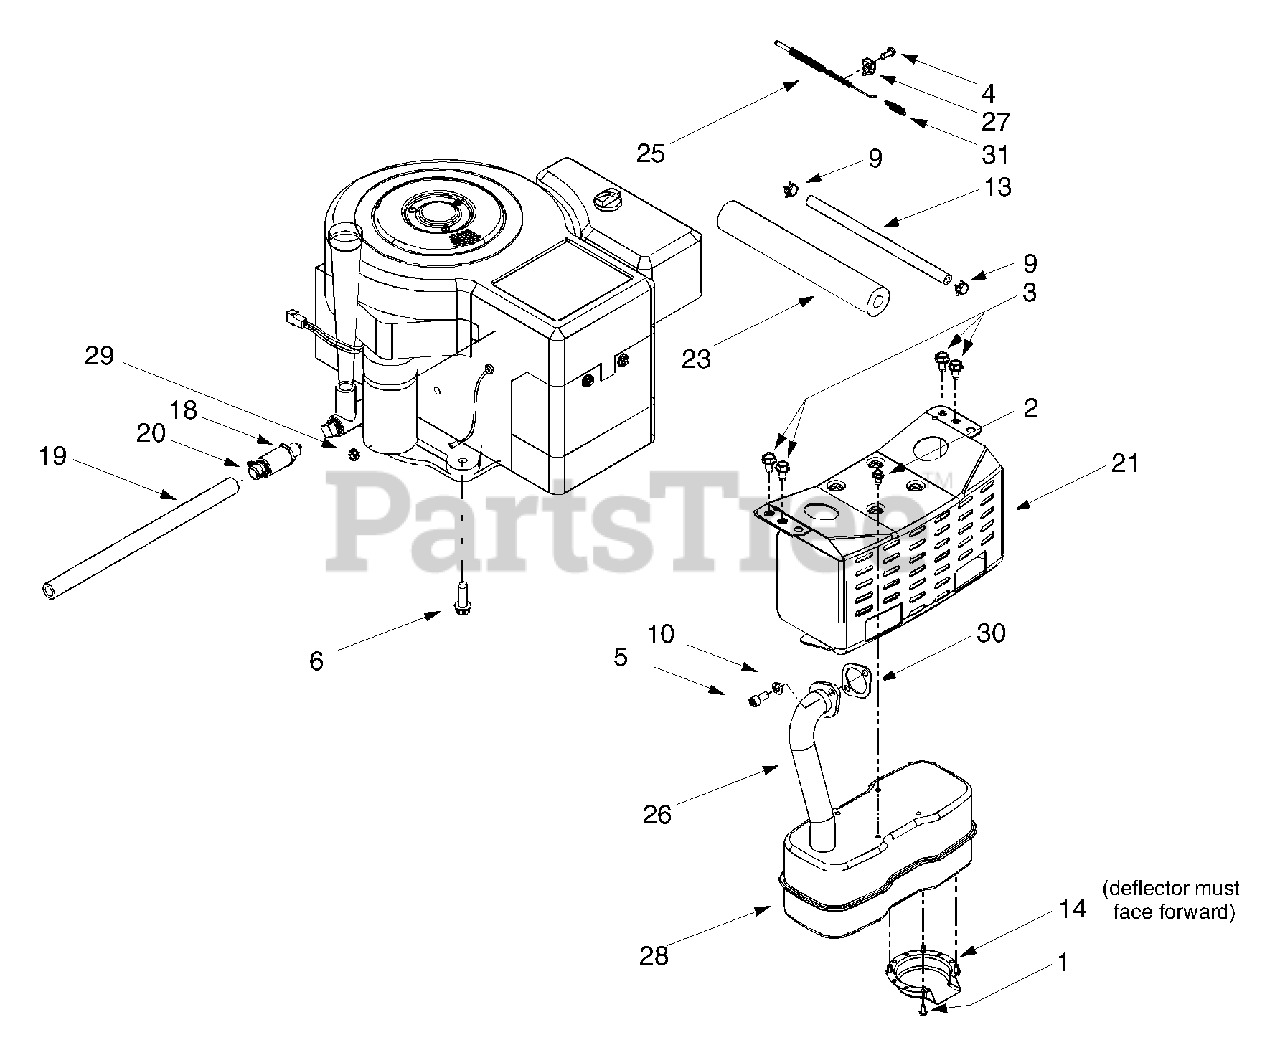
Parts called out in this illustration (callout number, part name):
1	Self-tapping Screw, #8-32 x .375
2	Self-tapping Screw, 1/4-20 x .5
3	Self-tapping Screw, 5/16-18 x .625
4	Screw, #10-32 x .625
5	Socket Cap Screw, 5/16-18 x .625
6	Self-tapping Screw, 3/8-16 x 1.25
10	Lock Washer, 5/16
13	Fuel Line Hose
14	Muffler Deflector
18	Oil Drain Valve
19	Oil Drain Hose
20	Oil Drain Cap
23	Foam
25	Throttle/Choke Cable (
26	Exhaust Pipe
27	Casing Clamp
28	Muffler, Single Inlet
29	Hex Sems Nut, 1/4-20
30	Exhaust Gasket
31	Extension Spring, .275 x 1.25
